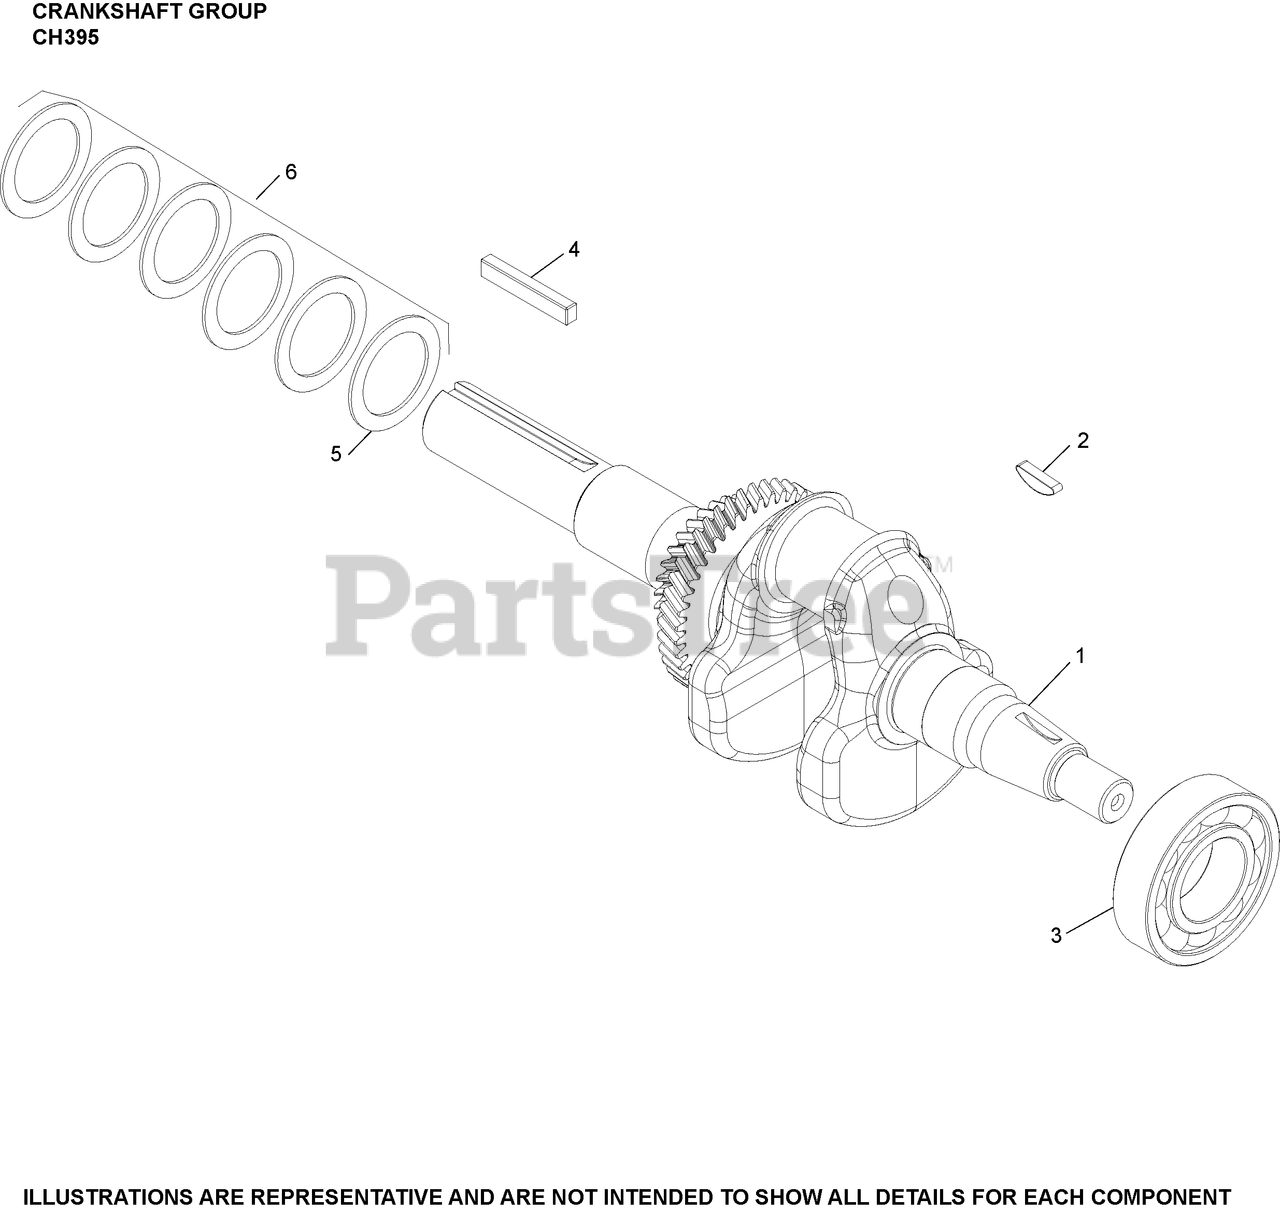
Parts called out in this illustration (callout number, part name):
1	CRANKSHAFT ASSEMBLY
2	KEY, FLYWHEEL
6	KIT, SHIMS
